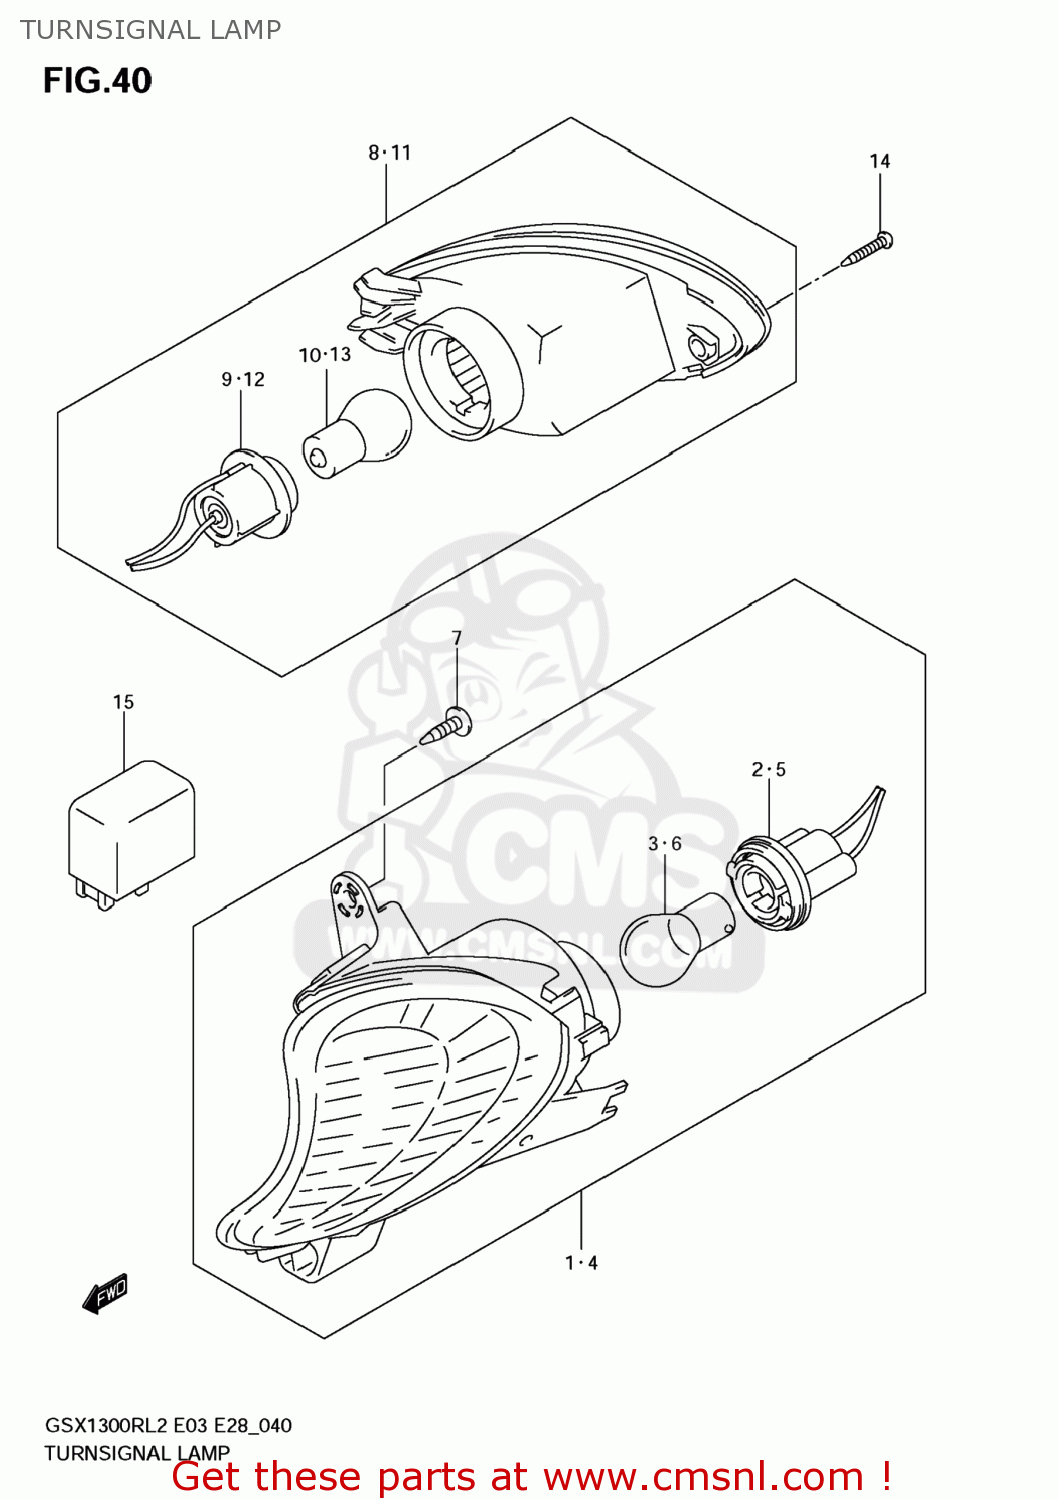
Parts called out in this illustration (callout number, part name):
1	LAMP ASSY,FR TURN SIGNAL,R
2	SOCKET & CORD,R
3	BULB(12V21W,AMBER)
4	LAMP ASSY,FR TURN SIGNAL,L
5	SOCKET & CORD,L
6	BULB(12V21W,AMBER)
7	SCREW
8	LAMP ASSY,RR TURNSIGNAL,R
9	SOCKET & CORD,R
10	BULB(12V21W,AMBER)
11	LAMP ASSY,RR TURNSIGNAL,L
12	SOCKET & CORD,L
13	BULB(12V21W,AMBER)
14	SCREW(4X20)
15	RELAY ASSY,TURNSIGNAL LAMP
